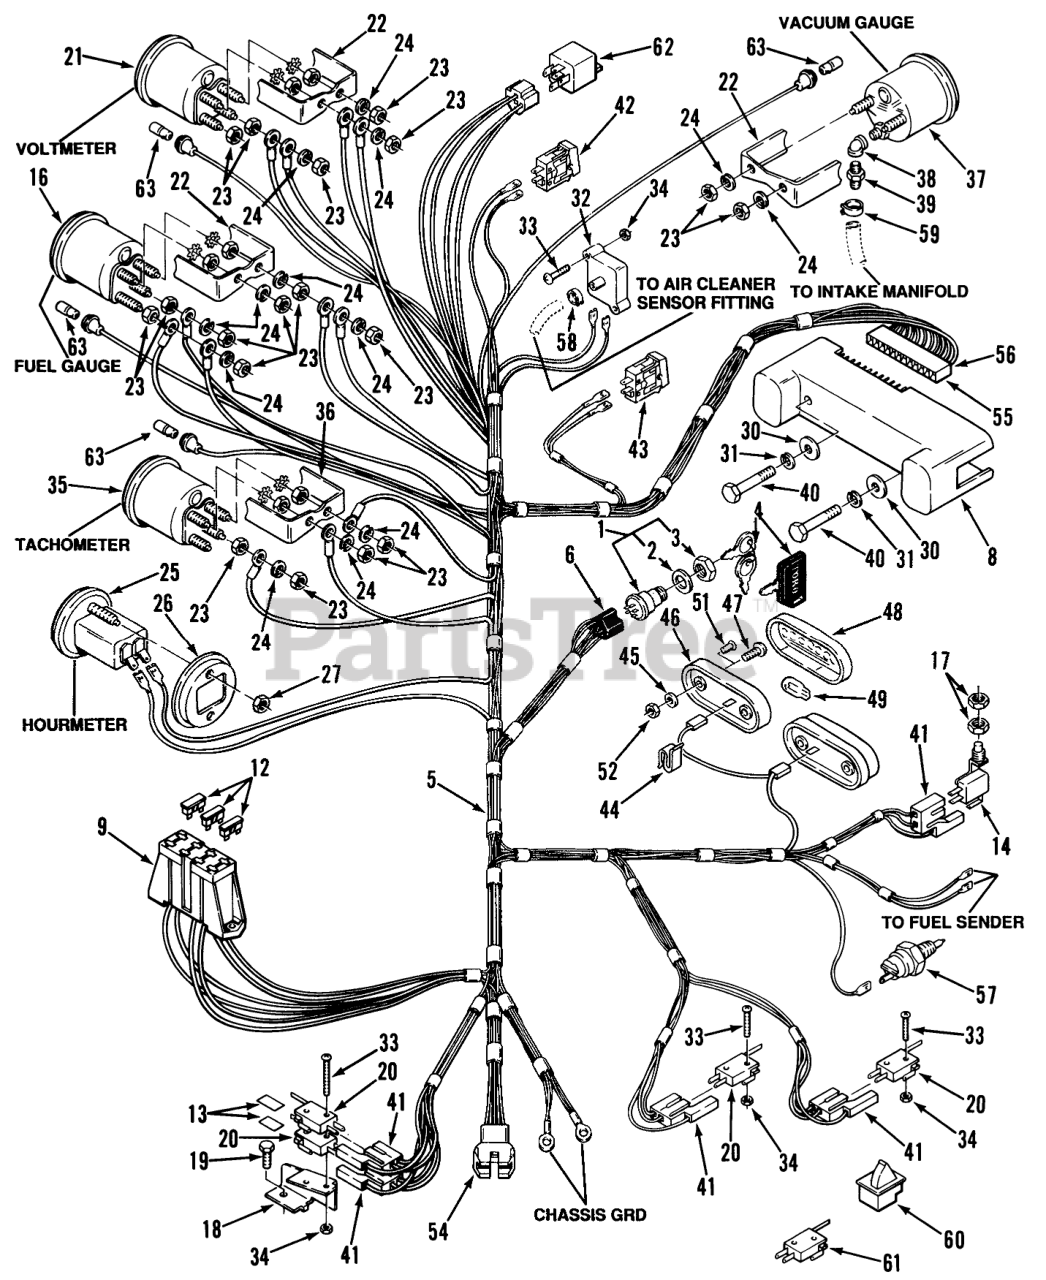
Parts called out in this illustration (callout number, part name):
1	IGNITION SWITCH ASM
2	Washer
4	Ignition Key
5	WIRING-HARNESS
6	CONNECTOR-5 WAY-SERV
8	8-Light Circuit Module 520-H
9	FUSE-HOLDER 4 WAY
12	FUSE-10 AMP
13	BARRIER - SWITCH
14	Seat Switch
16	Fuel Gauge (Includes item 22)
17	NUT-HEX, SPECIAL
18	Support-Switch
19	Bolt
20	SWITCH
21	Voltmeter (Includes item 22)
22	BRKT-GAUGE MOUNTING
23	Nut
24	Lockwasher
25	Hourmeter (Includes item 26)
26	BRKT-GAUGE MOUNTING
27	Hex Nut
30	WASHER
31	LOCKWASHER
32	SENSOR-AIR CLEANER
33	Screw
34	NUT HEX 4-40 ELAST
35	Tachometer (Includes item 36) 520-H
36	MOUNTING-BRACKET
37	Vacuum Gauge (Includes item 22) 520-H
38	ELBOW
39	FITTING STRAIGHT
40	SCREW
41	CONNECTOR BODY
42	Light Switch
43	SWITCH-TEST
44	SPEED CLIP
45	Lockwasher
46	BASE-TAIL LIGHT
47	Screw
48	LENS-TAIL LIGHT
49	LIGHT BULB
51	RIVET-4
52	Nut
54	9-CIRCUIT CAP
55	Connector-Male
56	Terminal
57	SENSOR-HYDRO OIL HOT
58	CLAMP-HOSE 5/16"
59	Clamp
60	SWITCH-INTERLOCK
61	SWITCH - CLUTCH
62	RELAY
63	LAMP-MINIATURE
